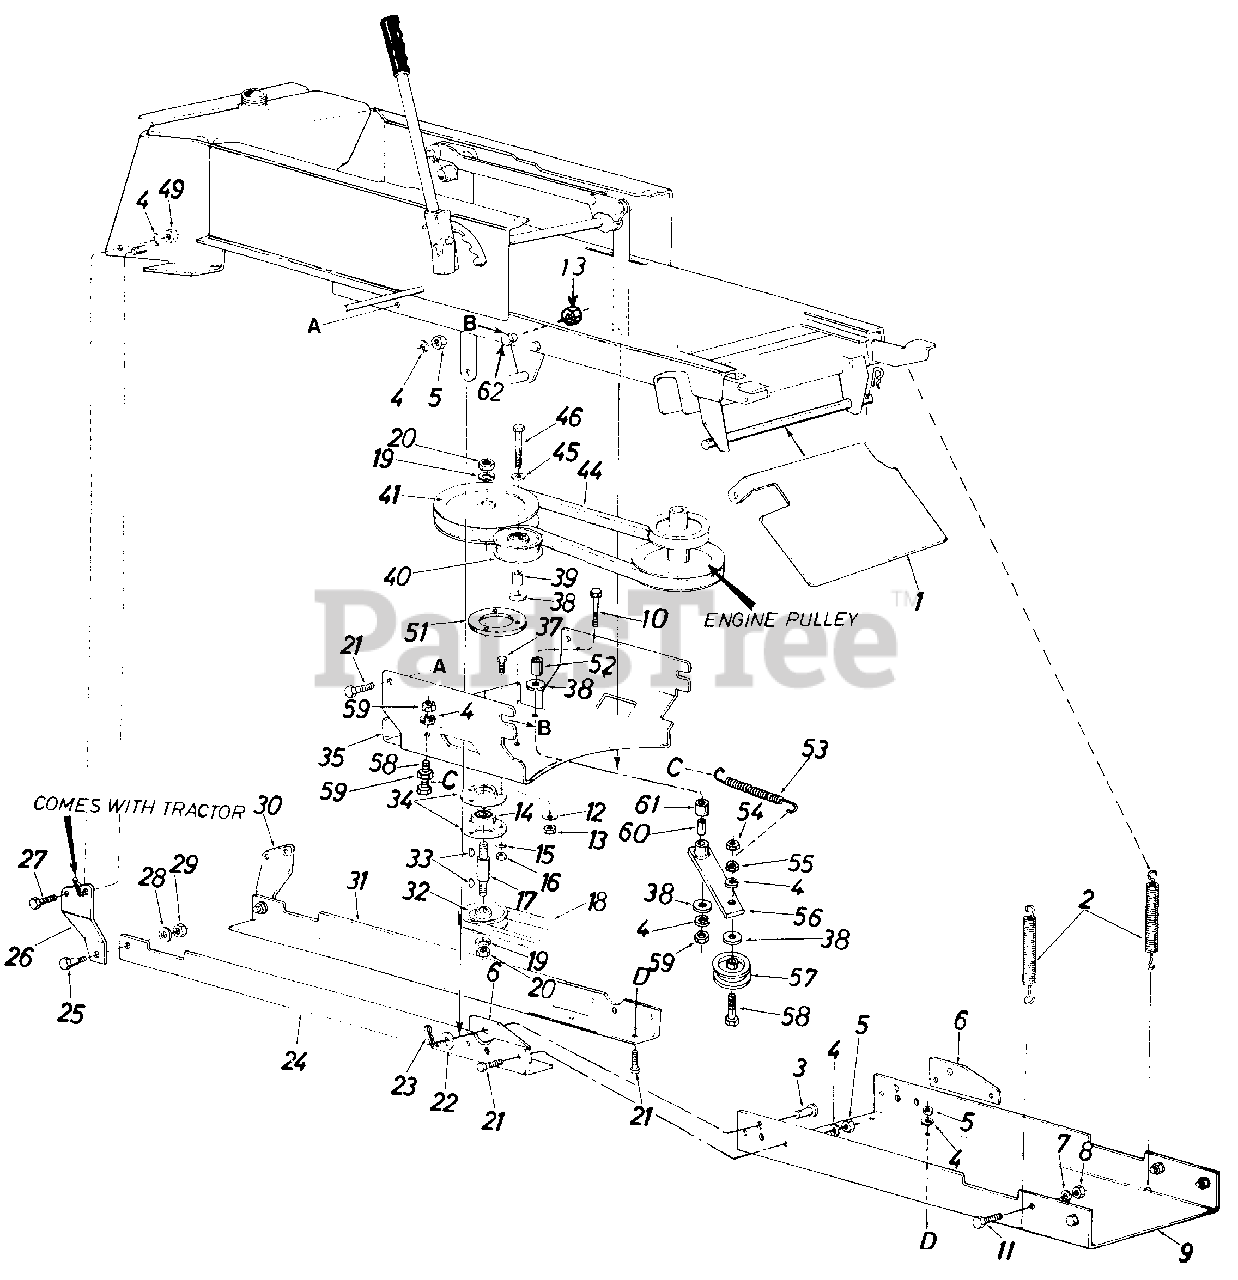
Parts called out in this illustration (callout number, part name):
1	Guide Bracket
2	Helper Spring
3	Clevis Pin
4	L.-Wash. 3/8" I.D.*
5	Hex L.-Nut 3/8-24 Thd.
6	Attaching Plate
7	L.-Wash. 1/2" I.D.*
8	Hex L.-Nut 1/2-20 Thd.
9	Front Support Channel
10	Hex Bolt 3/8-16 x 3.75" Lg.
11	Hex Bolt 1/2-20 x 1.25" Lg.*
12	Belleville Wash. 3/8" I.D.
13	Hex L.-Nut 3/8-16 Thd.
14	Ball Bearing
15	L.-Wash. 5/16" I.D.*
16	Hex Nut5/16-18 Thd.*
17	Spindle
18	" V "-Belt 1/2" x 85 x 2 (Kevlar)
19	L.-Wash. 5/8" I.D.*
20	Hex Jam Nut 5/8-11 Thd.
21	Hex Bolt 3/8-24 x 1.00" Lg.*
22	Flat Washer
23	Internal Cotter Pin
28	Fl.-Wash. .44" I.D. x 1.38" O.D. x .130
29	Hex L.-Nut 7/16-24 Thd.
30	Rear Hanger Brkt.-L.H.
33	#6 Hi-Pro Key 3/16 x 5/8" Dia.
34	Bearing Housing
35	Supporting Bracket
37	Hex Sems Bolt 5/16-18 x 1.00" Lg. *
38	Fl.-Wash. .38" I.D. x 1.00" O.D. x .135
39	Spacer .38" I.D. x .62" O.D.
40	Fl.-Idler Pulley
41	Upper Drive Pulley
44	"V"-Belt 1/2" x 49.8" Lg.
45	F l.-Wash.
46	Hex Bolt 3/8-16 x-2.50" Lg.*
49	Hex Nut 3/8-16 Thd.*
53	Extension Spring .54" O.D. x 5.25" Lg.
54	Hex Cent. L.-Nut 3/8-16 Thd.
55	Hex Jam Nut 5/8-11 Thd.
56	Idler Arm Ass'y.
57	Idler Pulley
58	Hex Bolt 3/8-16 x 2.25" Lg.
59	Hex Jam Nut 3/8-16 Thd.
60	Spacer.377" I.D. x .60" O.D. x.830" Lg.
61	Spacer.380" I.D. x .630" O.D. x.565" Lg.
62	Shld. Bolt .498" Dia. x .340"
